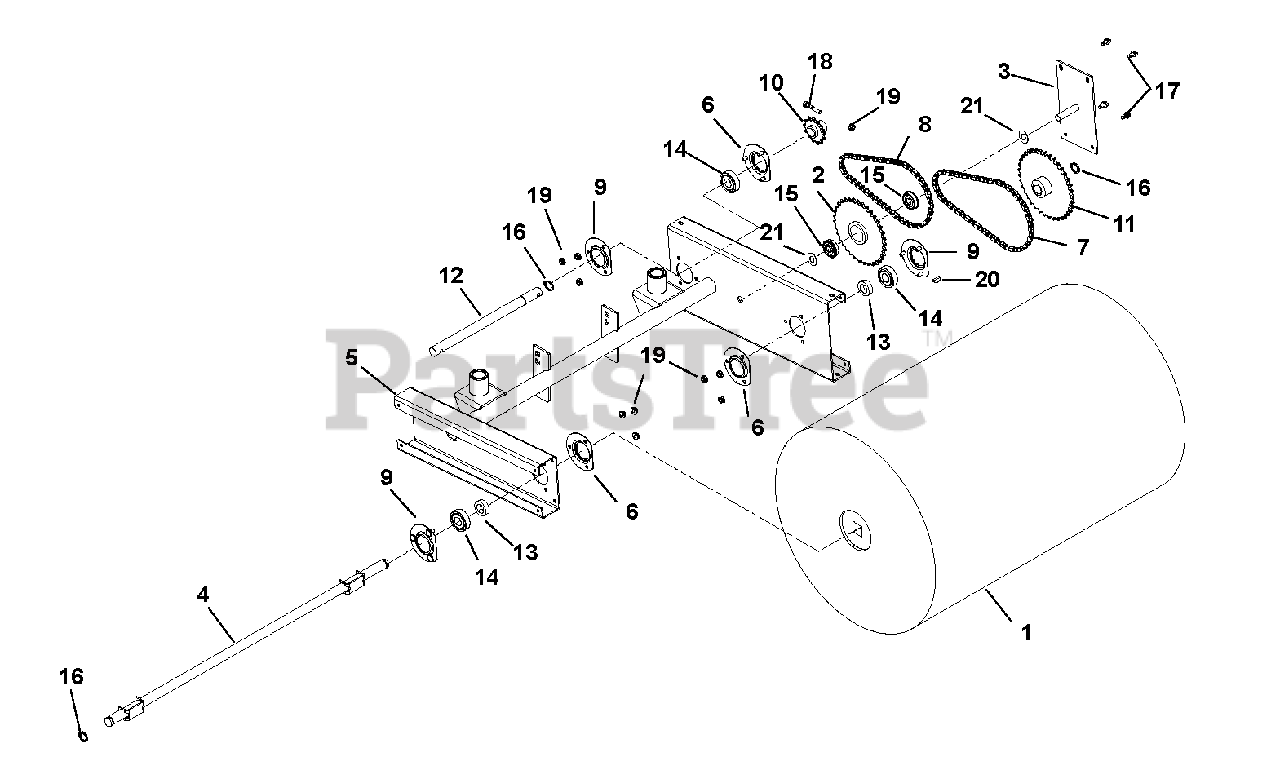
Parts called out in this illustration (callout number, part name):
1	Brush, 18" Diameter x 28" Wide
2	Sprocket, Reduction Idler
3	Mount, Reduction Idler
4	Shaft, Brush
5	Frame, Brush
6	Bearing Flange
7	Chain, Roller
8	Chain, Roller
9	Bearing Flange
10	Sprocket, Drive
11	Sprocket, Driven
12	Shaft, Transmission
16	Ring, Retaining, External .689 x .078
17	Screw, Tapping Hex Washer Head Thread Rolling .25-20 x .50
18	Bolt, Hex .25-20 x 1.75
19	Nut, Locking Top Flange .25-20
20	Key, Woodruff .188 x .75 x .313 SAE 9
21	Washer, Flat Steel .563 x 1.38 x .109
